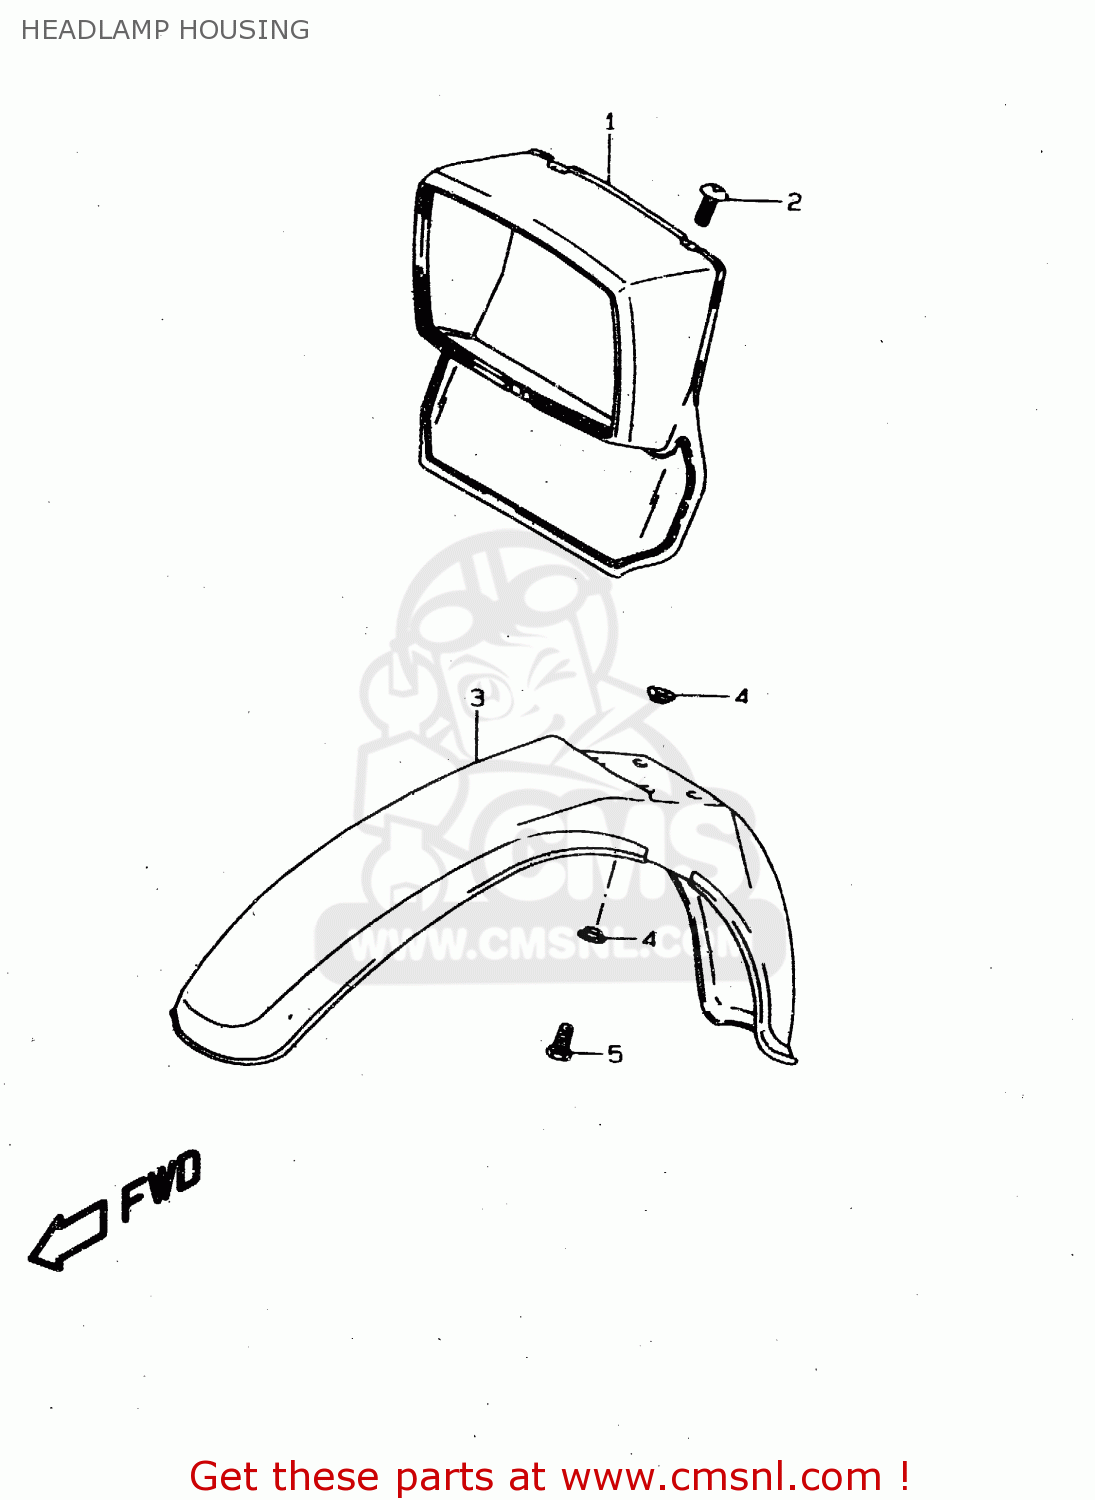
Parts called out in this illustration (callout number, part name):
1	HOUSING,HEADLAMP
2	SCREW 6X12
3	FENDER,FR
4	WASHER
5	BOLT
